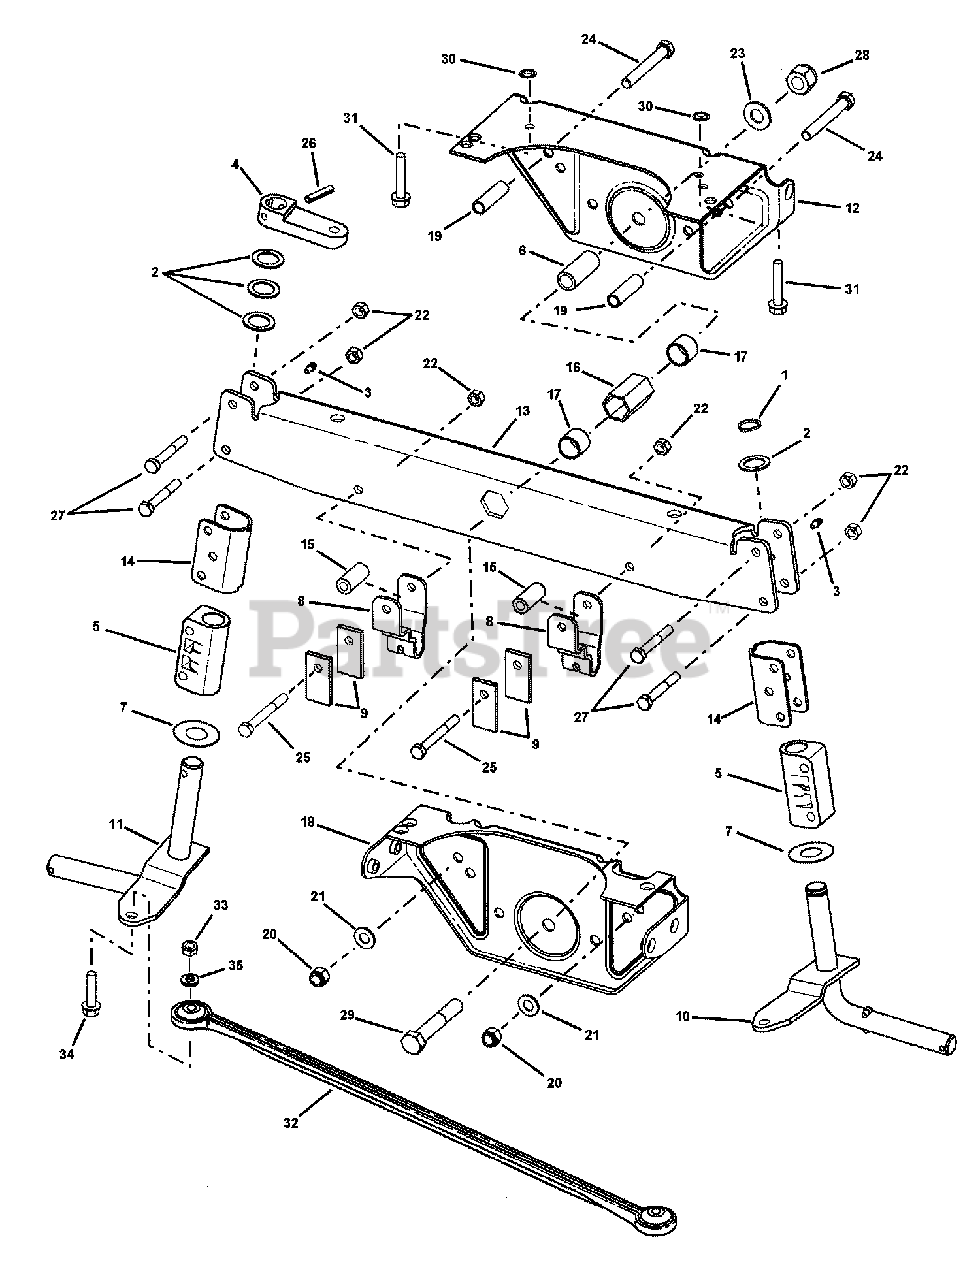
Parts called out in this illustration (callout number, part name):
1	RING, 3/4" External Retaining
2	WASHER, 3/4" x 1-1/8" Flat
3	LUBE FITTING 57352
4	ARM, Steering
5	BEARING, Spindle
6	SPACER, .5 x .75 x 1.78
7	THRUST WASHER
8	BRACKET, Deck Hanger-Front Axle.
9	SPACER, Steering Stop, Cast Axle
10	WELDMENT, Right Hand Spindle Wheel
11	WELDMENT, Left Hand Spindle Wheel
12	BRACKET, Cast Axle Front
12	BRACKET, Cast Axle, Front
13	AXLE, Steel- Tractor
14	SPACER, Spindle Bearing- Steel Axle
15	SPACER, Axle- Steel
16	SPACER, Hex
17	BEARING, 3/4" I.D. DX
18	BRACKET, Cast Axle, Rear
19	SPACER, .39 x .5 x 1.72
20	NUT, 3/8-16 Hex Nyloc
21	WASHER, 3/8" Flat SAE
22	NUT, 5/16-18 Hex Center Lock
23	WASHER, 1/2" Flat
24	SCREW, 3/8-16 x 2-3/4" Hex Head Cap, GR2
25	SCREW, 5/16-18 x 2-3/4" Hex Head Cap, GR5
26	ROLL PIN, 1/4 x 1-1/4"
27	SCREW, 5/16-18 x 2" Hex Head Cap, GR5
28	NUT, 1/2-13 Hex Nyloc
29	SCREW, 1/2-13 x 3" Hex Head Cap, GR5
30	RETAINER, 5/16" Bolt
31	BOLT, 5/16-18 x 1-3/4" Hex Flange Lock, GR5
32	TIE ROD, Reduced Radius
33	NUT, 3/8-16 Hex , GR5 or B
34	SCREW, 3/8-16 x 1-1/2" Hex Head Cap, GR5
35	WASHER,3/8" Split Lock
